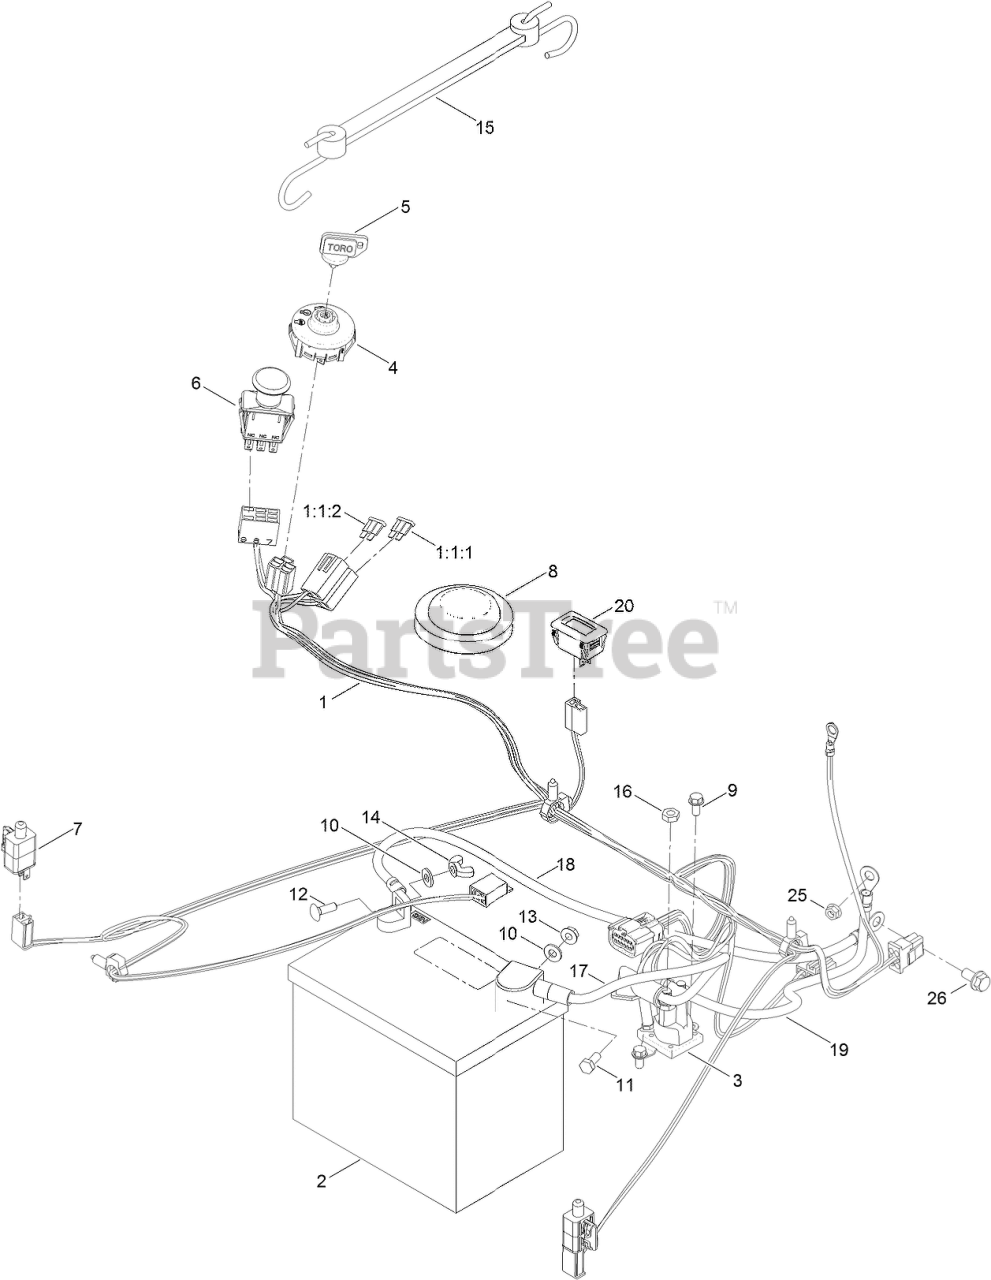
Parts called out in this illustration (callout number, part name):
1	HARNESS-WIRE
1:1:1	FUSE-BLADE, 30 AMP
1:1:2	FUSE-BLADE, 25 AMP
2	BATTERY
3	SOLENOID
4	SWITCH-IGNITION
5	KEY-IGNITION
6	SWITCH-PTO
7	SWITCH
8	SWITCH-SEAT
9	SCREW-HWH
10	WASHER-FLAT
11	SCREW-HH
12	BOLT-CARR
13	NUT-HF
14	NUT-WING
15	HOLDDOWN-BATTERY
16	NUT-JAM
17	CABLE-BATTERY, RED
18	CABLE-BATTERY, POSITIVE
19	CABLE-BATTERY, BLACK
20	HOURMETER
25	NUT-HF
26	SCREW-HHF
